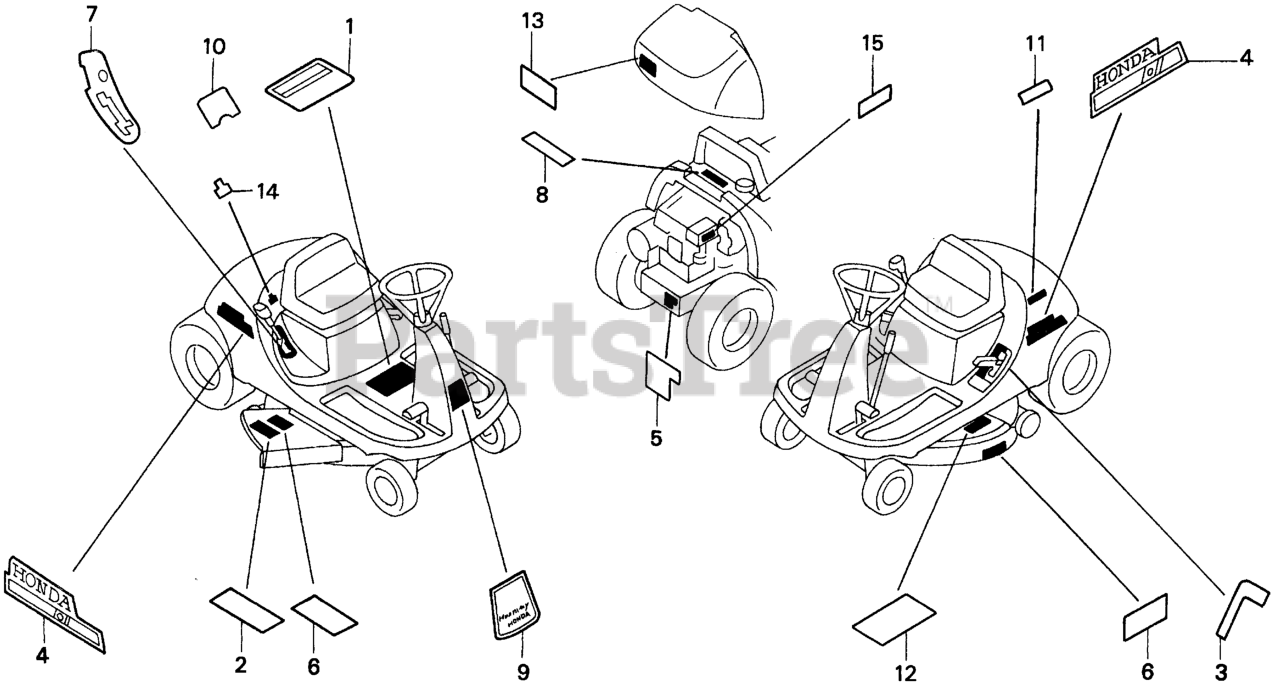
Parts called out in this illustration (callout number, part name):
1	LABEL, OPERATION
2	LABEL, WARNING (A)
3	MARK, HEIGHT INDICATION (A)
4	MARK, STRIPE (A)
5	LABEL, MANUAL (A)(H.S.T.)
6	MARK, DANGER (A)
7	MARK, CONTROL OPERATION (A)
8	MARK, OWNER'S MANUAL OPERATION (A)
9	MARK, FR. EMBLEM
12	LABEL, CAUTION (A)
13	LABEL, HEAT WARNING
15	DECAL, FUEL VALVE
